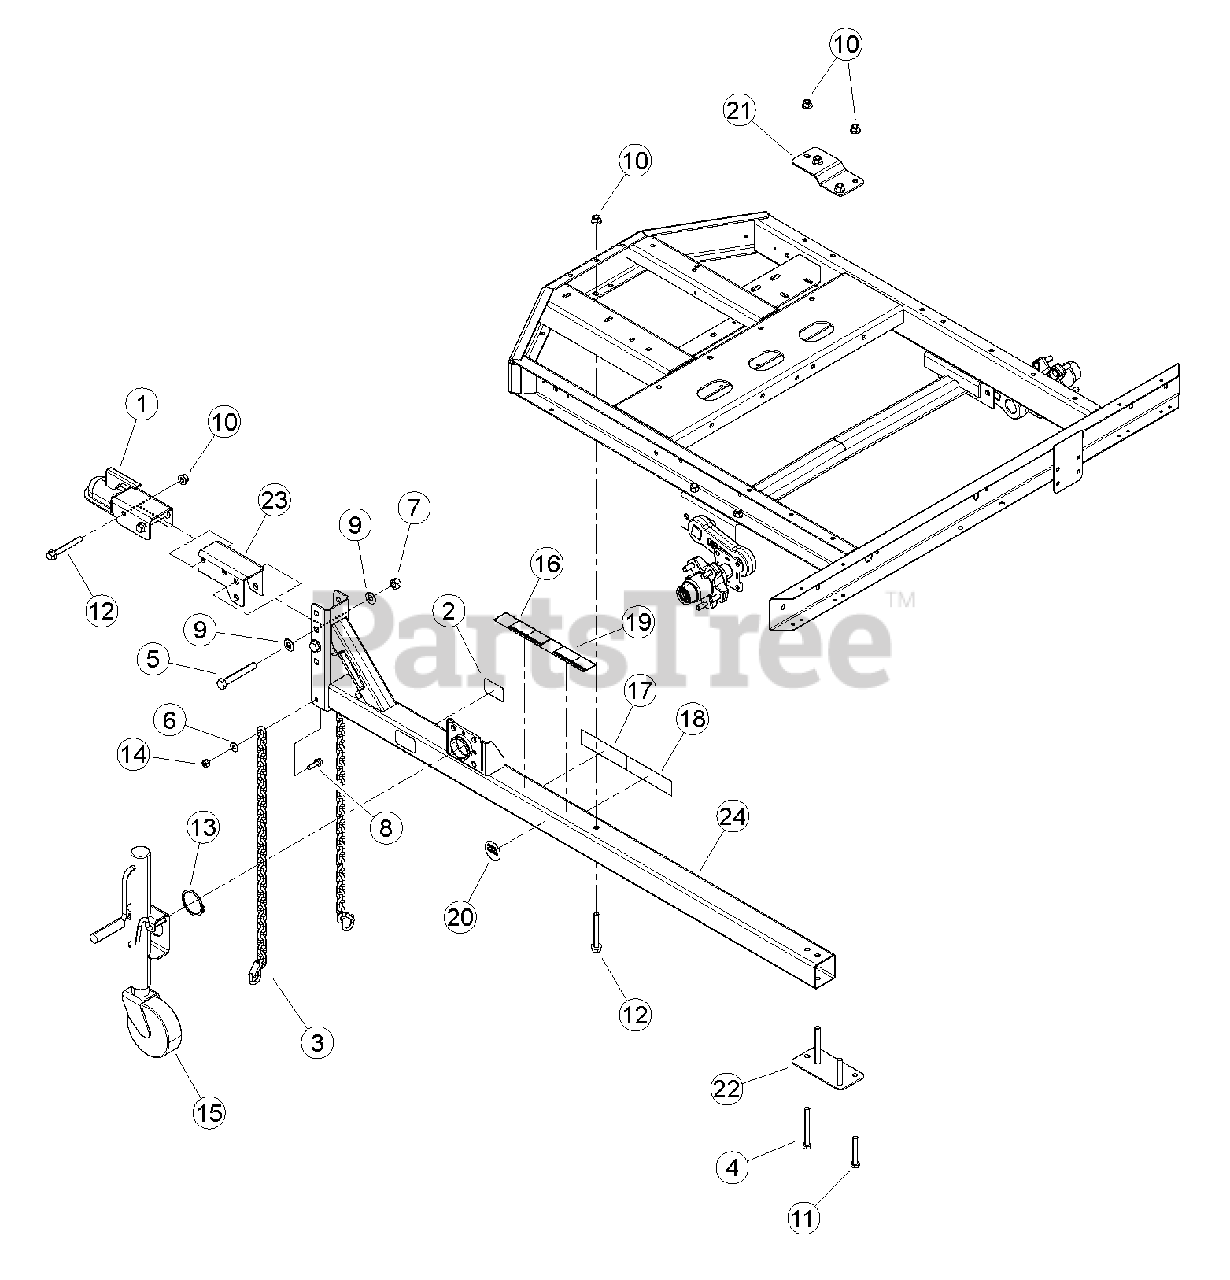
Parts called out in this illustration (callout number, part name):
1	COUPLER, 2 IN
2	REFLECTOR, WIDE ANGLE AMBER
3	CHAIN, SAFETY 5000 LB W/ LATCH
4	BOLT, 1/2 X 4-1/2" GR5 HHCS NC ZP
5	BOLT, 5/8 X 4-1/2 HEX HD G5 ZP
6	WASHER, 3/8 FLAT
7	NUT, 5/8" CENTERLOCK ZP GR5
8	BOLT, 3/8 X 1-1/4 FLANGE NC
9	WASHER, 5/8 SAE FLAT
10	NUT, 1/2-13 NYLOCK FLANGE
11	BOLT, 1/2 X 3-1/4 HCS GR5 ZP
12	BOLT, 1/2-13 X 4 FLANGE GR5 CZP
13	RING, 2-1/2 EXTERNAL SNAP
14	NUT, 3/8-16 NYLOCK FLANGE
15	JACK, PIVOTING W/ SWIVEL CASTOR
16	DECAL, SAFETY CHAINS
17	DECAL, TRAILER ELECTRICAL
18	DECAL, CHECK WHEELS
19	DECAL, SAFE COUPLING
20	DECAL, NATM COMPLIANCE
21	PLATE, AXLE SAFETY
22	PLATE, AXLE SAFETY
23	MOUNT, COUPLER
24	WELDMENT, HITCH POLE
